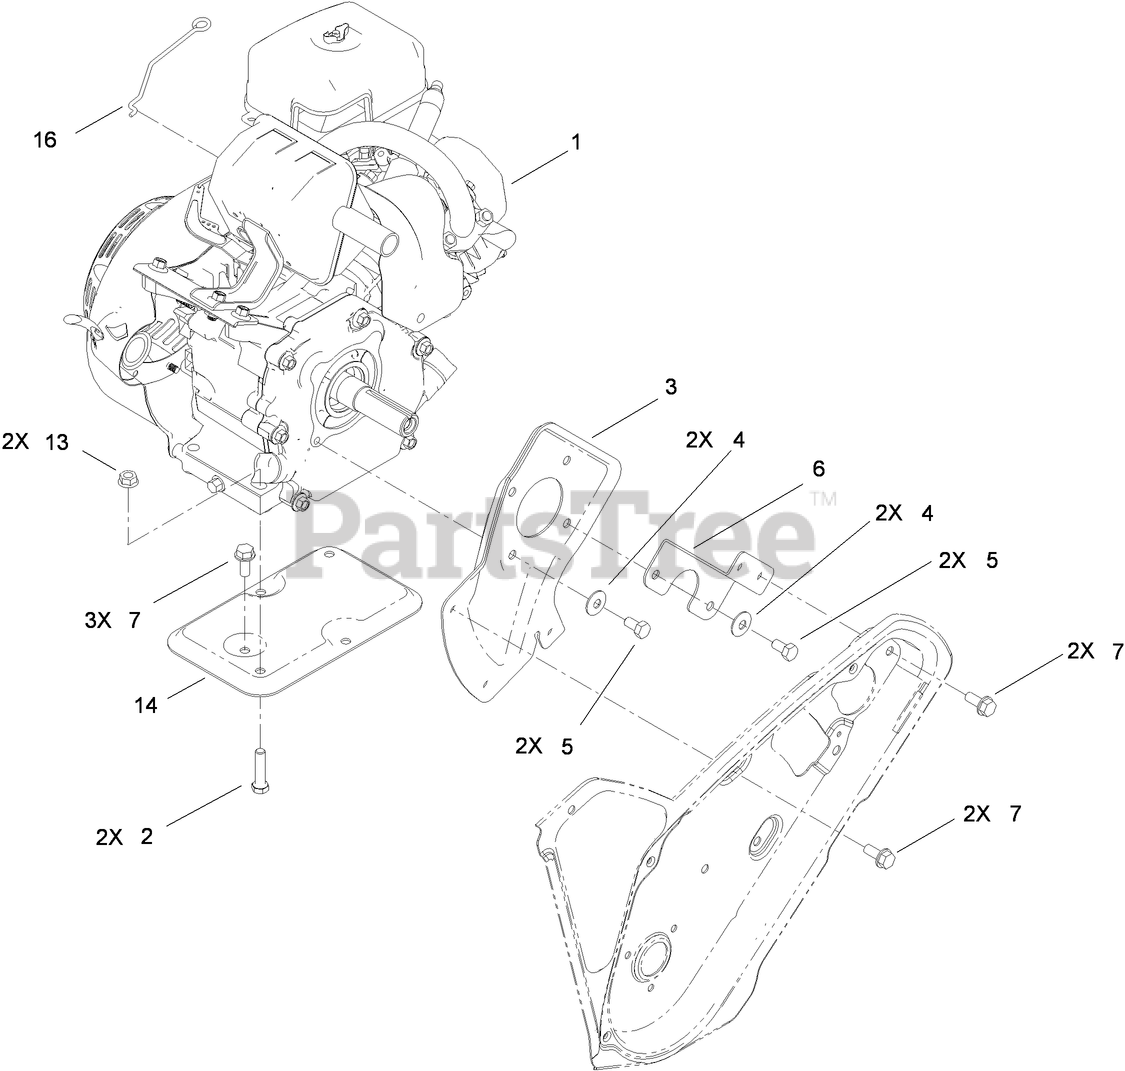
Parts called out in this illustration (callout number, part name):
1	ENGINE-168FS-1
2	SCREW-HH
3	PLATE-ENGINE, PTO
4	WASHER-BELLEVILLE
5	SCREW-HHF
6	SUPPORT-ENGINE, SIDE
7	SCREW-THD ROLL, HWH
13	NUT-HF
14	SUPPORT-ENGINE
